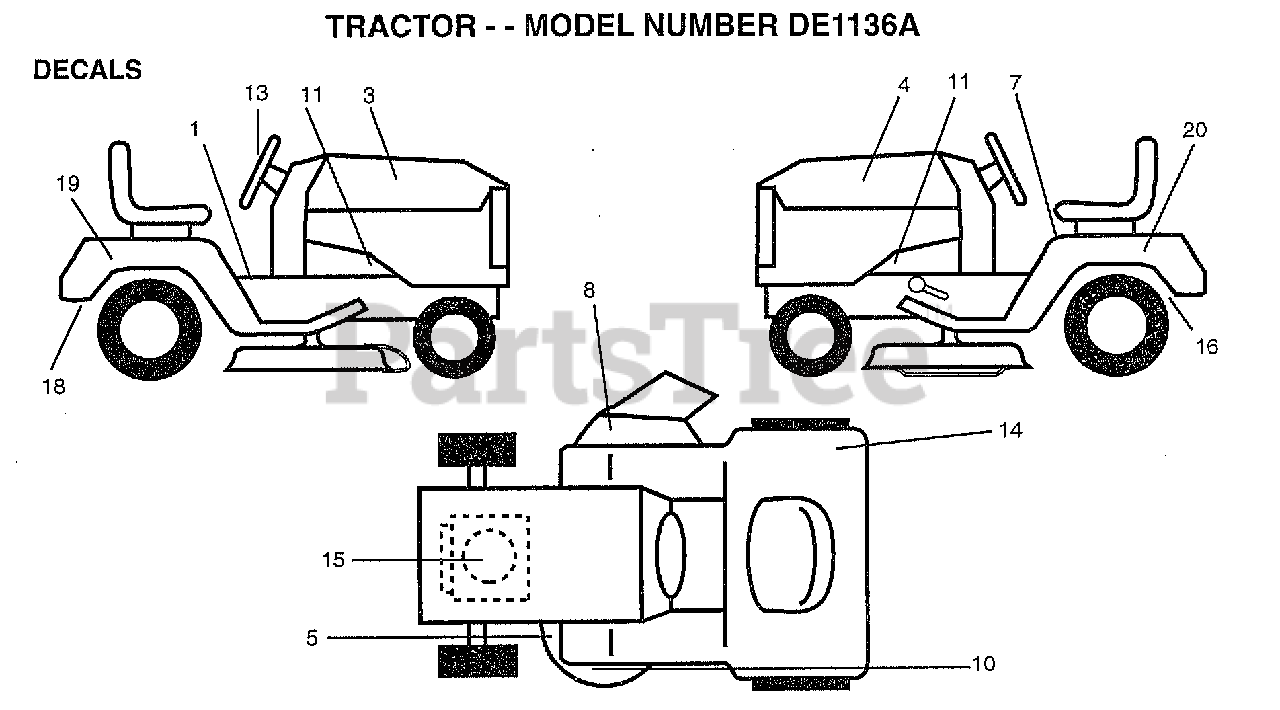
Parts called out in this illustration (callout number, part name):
1	DECAL CLUTCH/BRAK
3	DECAL.HOOD.RH
4	DECAL.HOOD.LH
5	DECAL.V.BELT
7	DECAL.READ.O.MANU
8	DECAL.DANGER.CUTF
10	DECAL.DECK.MOWER
11	"DECAL CHASSIS,HOT"
12	DECAL.BATRY.3-3908
13	DECAL.INST.STEERING
16	DECAL.DRAWBAR.LDL
18	DECAL.EURO.ST.CE.
19	DECAL.FENDER.RH
20	DECAL FENDER LH
